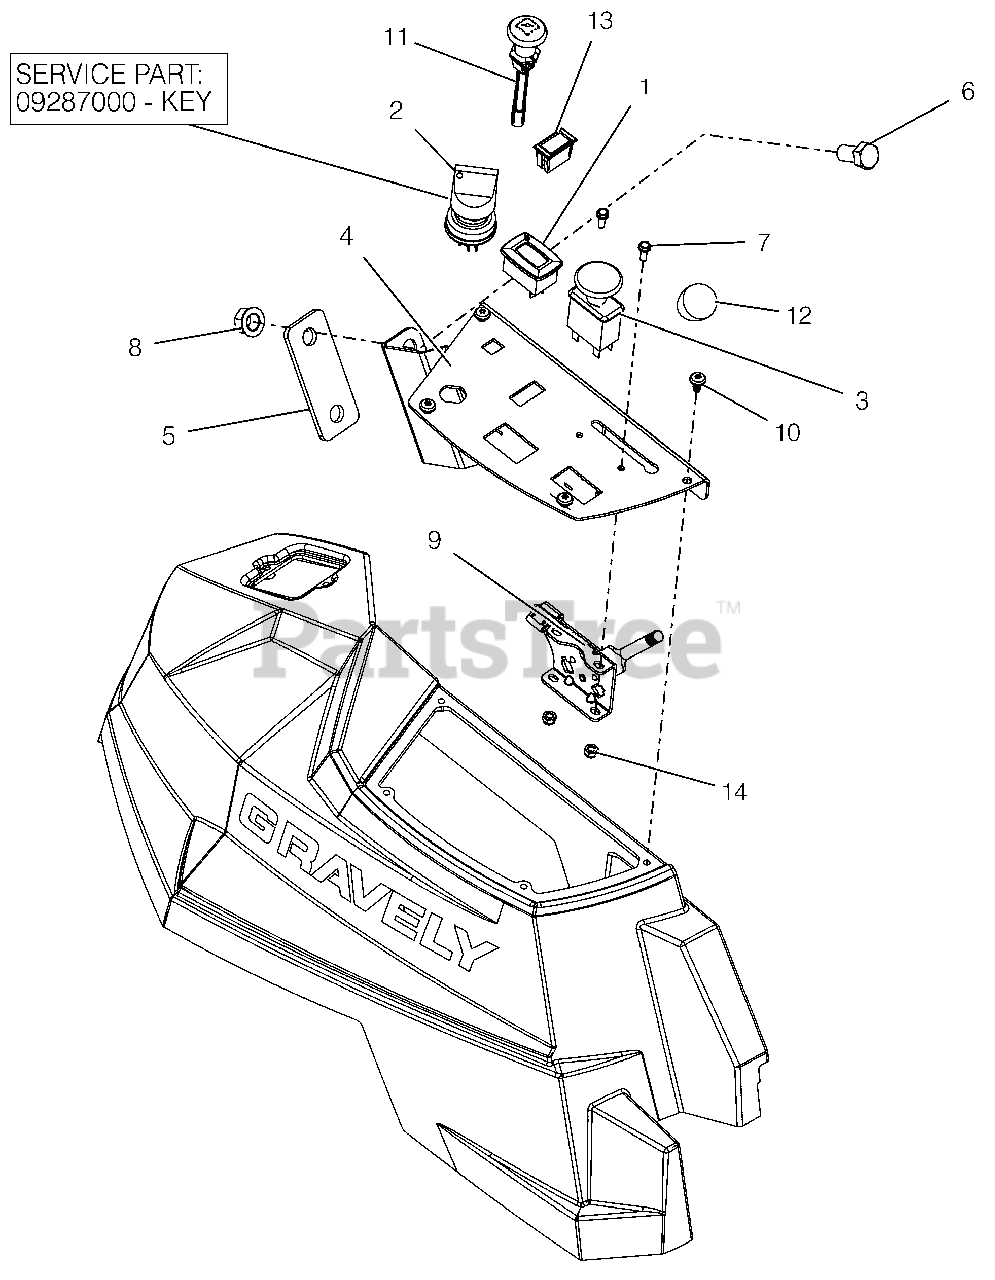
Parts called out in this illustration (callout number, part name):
1	METER, HOUR W/MAINTENANCE
2	SWITCH, IGNITION
2	KEY, W/ SHIELD
3	SWITCH, CLUTCH
4	PANEL, HD CONTROL
5	PLATE, CONTROL PANEL SPACER
6	@BLT-HEX .50-13X1.00 GR5 YWZC
7	@SCR-MCH 10-24X.50 HWH YWZC
8	@NUT-LK-TOP-FLG .50-13 YWZC
9	CABLE, PRO THROTTLE CONTROL
10	SCR-PAN .25-15X.50 6L H/LZB500
11	CABLE - CHOKE, SNAP-IN
12	KNOB-CONTROL-BLACK .38-16X.50
13	SWITCH,BLANK
14	@NUT-LK-NYL 10-24 W/INSRT YWZC
